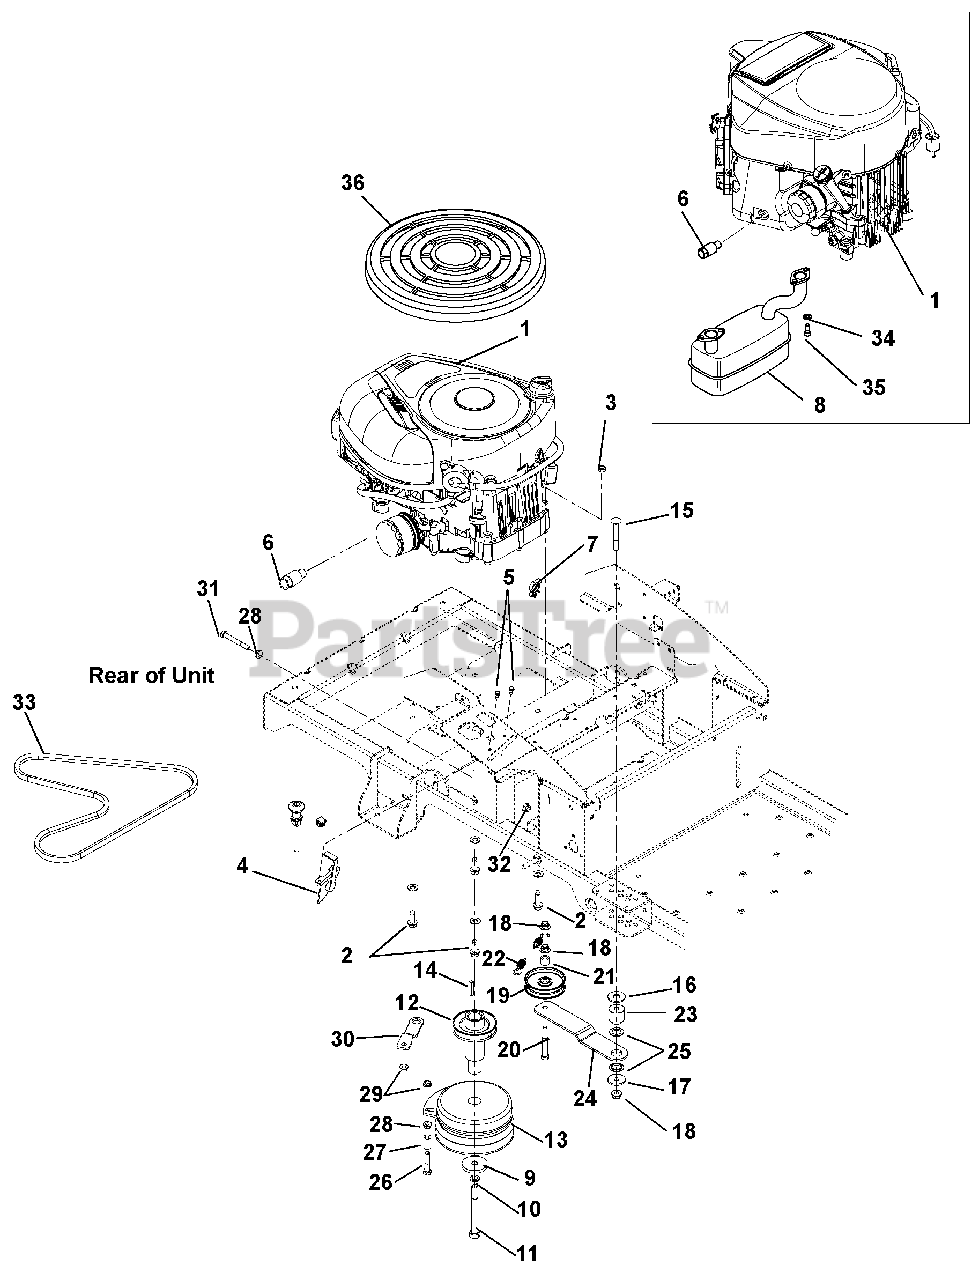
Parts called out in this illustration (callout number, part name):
1	Engine, 16HP V-Twin CE (915327)
2	Screw, Tapping .38-16 x 1.25 Hex Washer Head
3	Nut, Locking Jam .375-16 (915327)
4	Throttle/Choke Cable (915327)
5	Screw, Tapping 10-24 x .50 Hex Washer Head
6	Oil Drain
7	Wire Clip (for .25" hole)
8	Muffler, Twin Briggs
9	Washer, Flat Steel .469 x 2.00 x .25
10	Washer, Locking .44 x .109 Regular
11	Bolt, Hex .44-20 x 4.50 Grade 8
12	Weldment, Crankshaft Extension
13	Clutch, 105 FT*LB MONO Pole
14	Key, Square .25 x 1.25 x .25 SAE 8630 or SAE 1035
15	Bolt, Round Head Square Neck .38-16 x 2.75
16	Washer, Flat Steel .563 x 1.38 x .109
17	Washer, Flat Steel .406 x 1.375 x .135
18	Nut, Locking Nylon Flange .38-16
19	Pulley, Engine Clutch
20	Bolt, Hex .38-16 x 2.75
21	Bushing, Sleeve .391 x .688 x .52
22	Spring, Extension
23	Spacer, Ground Drive Idler
24	Idler Arm, Ground Drive
25	Bushing, Idler Arm
26	Screw, Cap .31-18 x 1.75
27	Spacer, Rubber 5/16 ID x 1.0
28	Nut, Spin Lock Flange .312-18
29	Nut, Locking Top Flange .31-18
30	Bracket, Clutch Stop
31	Bolt, Hex .31-18 x 2.75
32	Nut, Locking Nylon Flange .31-18
33	V-Belt, HA-RAW Edge Laminated
34	Washer, Locking .31 x .078 Regular
35	Capscrew .31-18 x .75 S/HD
36	Guard, Briggs Engine
